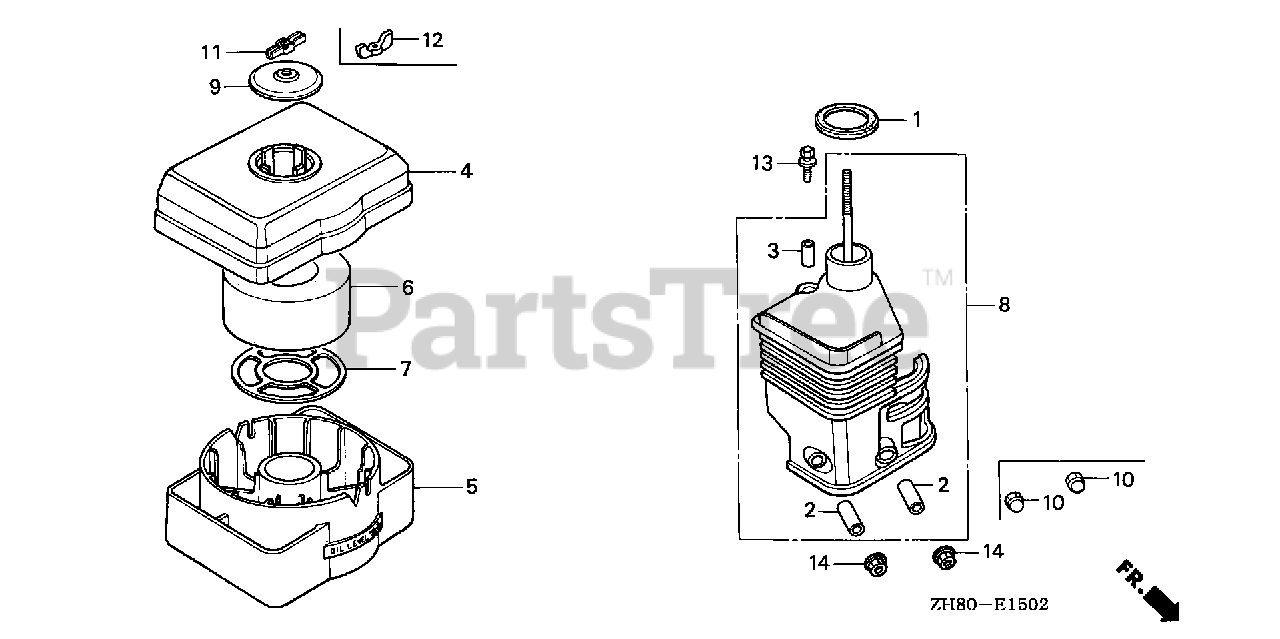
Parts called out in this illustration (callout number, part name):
1	GASKET, ELBOW
2	COLLAR, AIR CLEANER
3	COLLAR B, AIR CLEANER
4	BODY, CLEANER (OIL BATH)
5	PAN, CLEANER OIL (OIL BATH)
6	ELEMENT, AIR CLEANER (OIL BATH)
7	GRID, AIR CLEANER
8	ELBOW, AIR CLEANER
9	CAP, CLEANER
10	NUT, CAP (6MM)
11	NUT, AIR CLEANER COVER (DACRO COATING)
11	WINGNUT (6MM) (BLACK)
12	NUT, TOOL BOX SETTING
13	BOLT-WASHER (6X20)
14	NUT, FLANGE (6MM)
